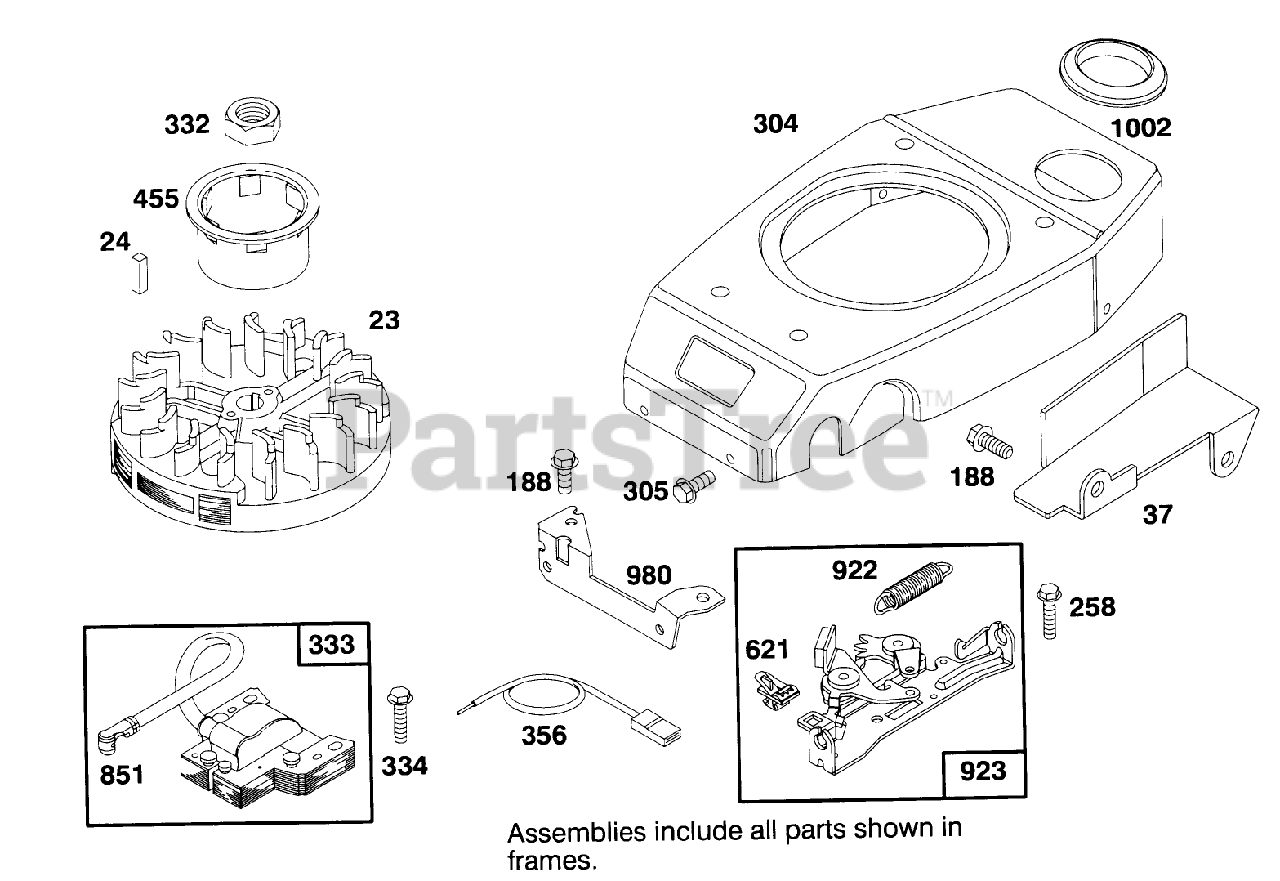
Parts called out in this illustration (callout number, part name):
24	KEY - FLYWHEEL
37	GUARD - FLYWHEEL
304	HOUSING - BLOWER
305	SCREW - HEX HEAD
332	NUT - HEXAGON
334	SCREW - SEM
356	WIRE - GROUND
621	STOP SWITCH
980	BRACKET-BLOWER HSG
